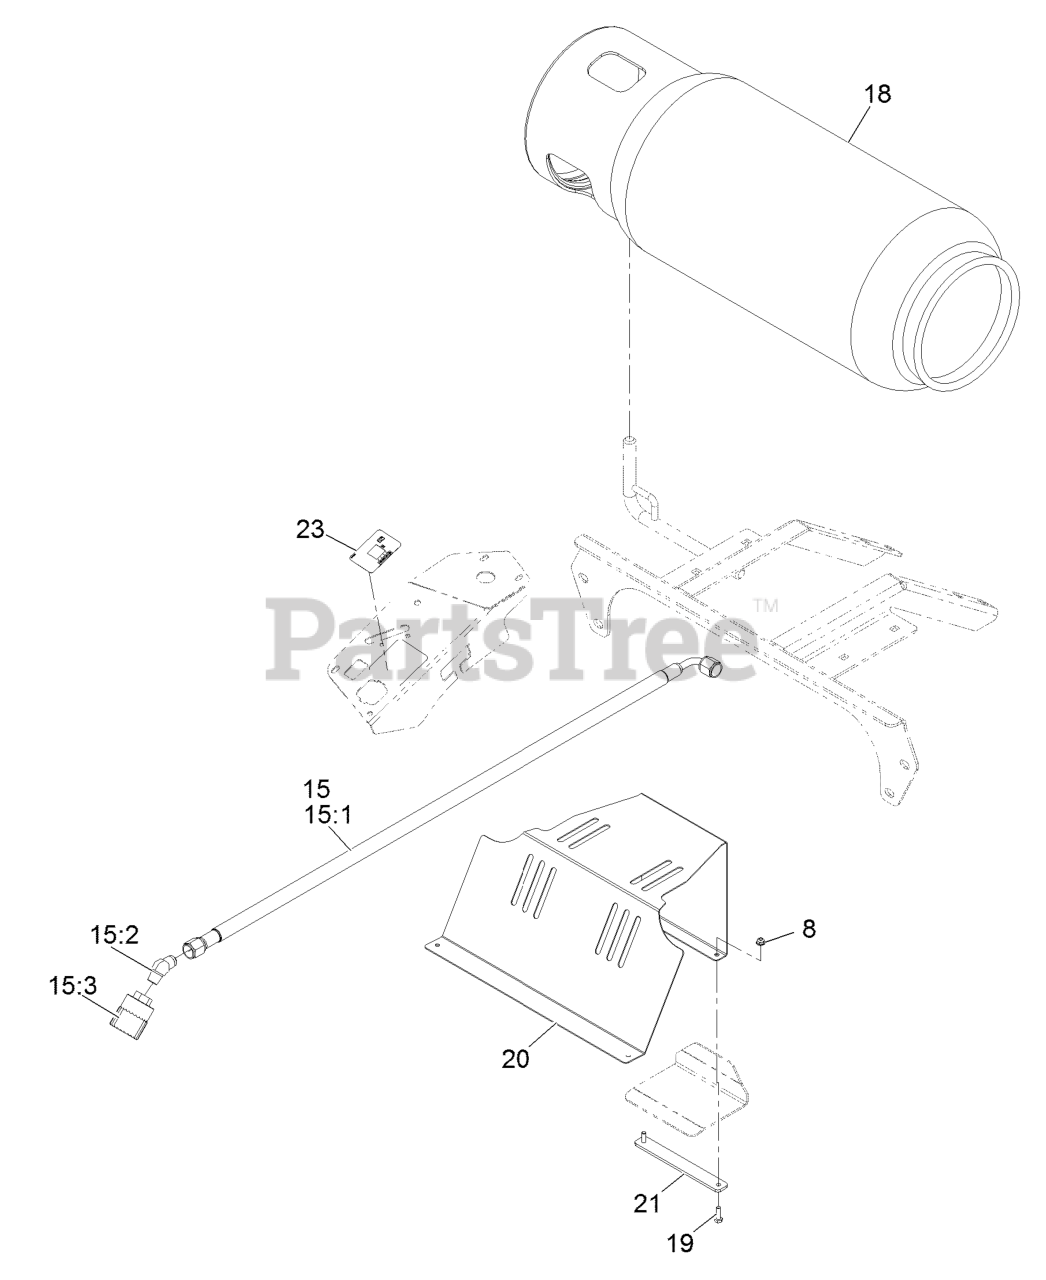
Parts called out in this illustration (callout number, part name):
15	Asm-Lpg Hose
15:1	LPG FUEL HOSE ASM
15:2	ELBOW-45 DEG
15:3	CONNECTOR-LPG TANK, LH TH
19	SCREW-HH
20	SHEILD-FAN
23	DECAL-METER, HOUR
